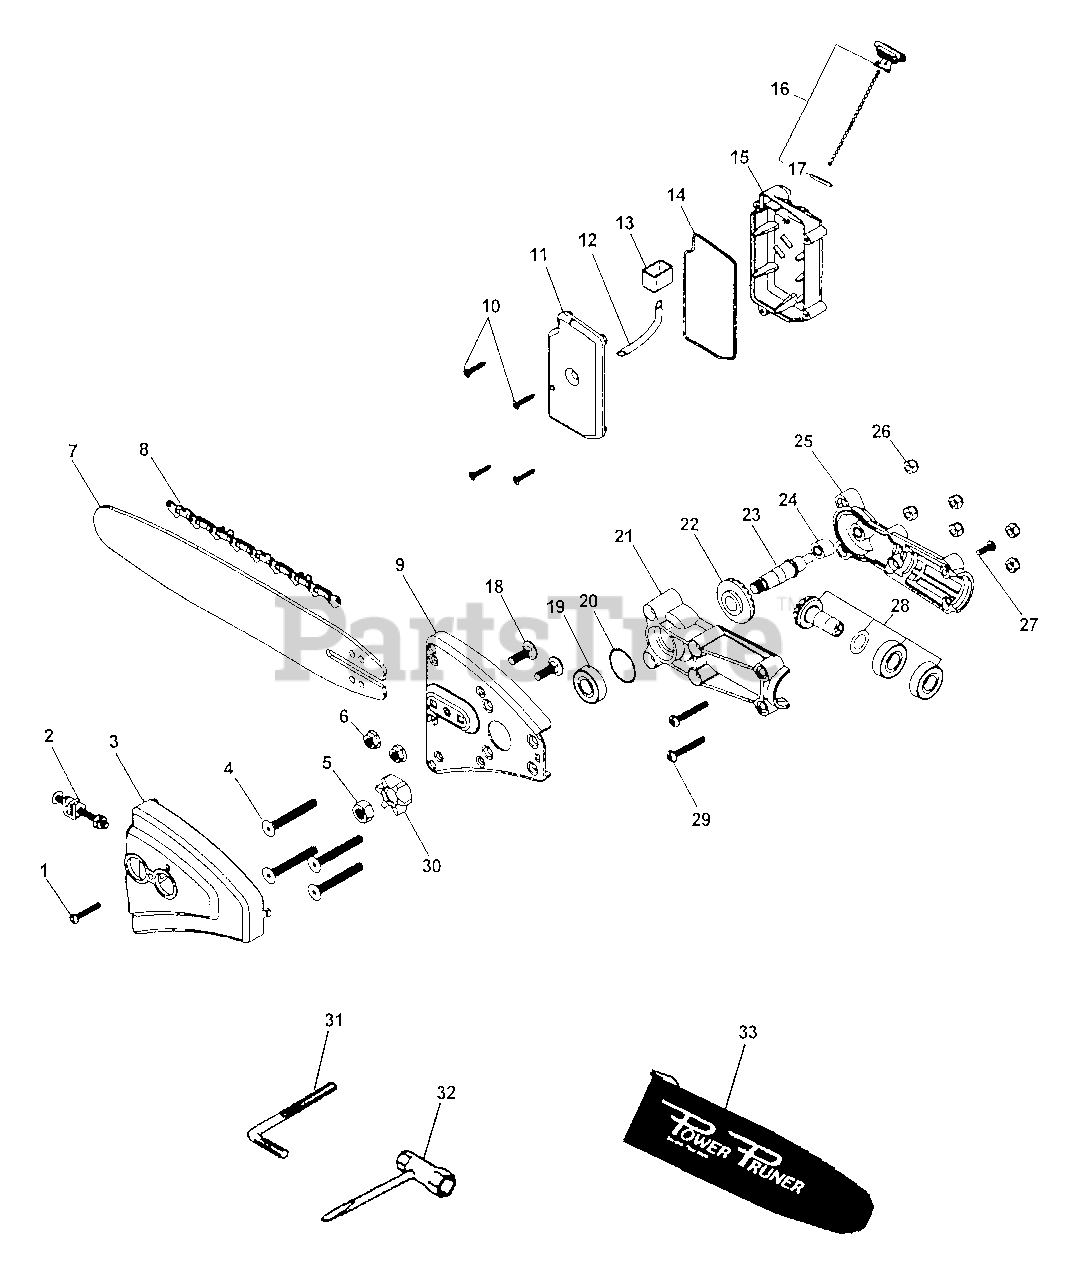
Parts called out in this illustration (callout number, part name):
1	SCREW - 8-32×1" - TORX PAN HEAD
2	TENSIONER KIT
3	GUARD, SPROCKET
4	SCREW - TORX FLAT HEAD
5	NUT, HEX
6	NUT - FLANGE
7	GUIDE BAR - 10"
8	SAWING CHAIN - 90SG - 10" -- MICRO-LITE
9	SAW BAR CARRIER
10	SCREW, PH. F.H. M.S.
11	TANK, OIL
12	PIPE, FUEL 3x-5x-70 BLACK
13	CUP, OIL
15	TANK, OIL
16	CAP, OIL
18	BOLT, CARRIAGE
19	BEARING, BALL 6001 DDU
20	SHIM 0.004"
21	CASE, GEAR - RIGHT
22	GEAR, BEVEL
23	SHAFT, GEAR
24	GUIDE, DRIVESHAFT
25	CASE, GEAR - RIGHT
26	NUT, LOCK 10-24 UNC
27	SCREW - TORX PAN HEAD
28	SHAFT, GEAR
29	SCREW, TORX 10-24 UNC 1-1/4
30	SPROCKET
31	TOOL, DRIVER
32	TOOL, BOX SPANNER
33	COVER, GUIDE BAR
